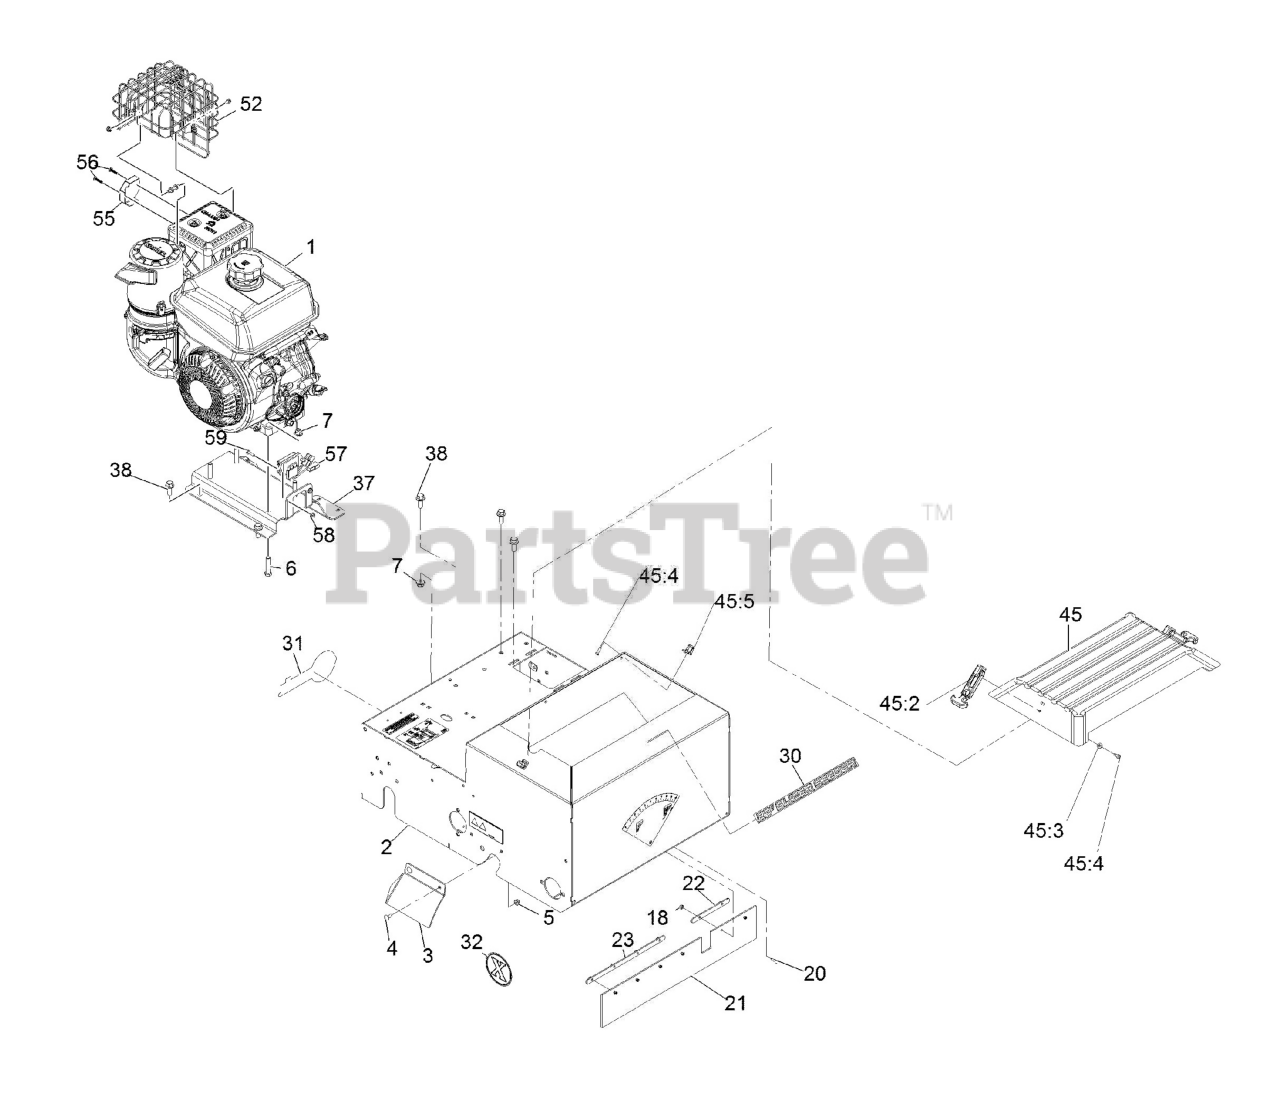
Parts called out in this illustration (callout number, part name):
2	FRAME ASM
4	SCREW-CARR
6	SCREW-HH
7	NUT-HF, NI
18	NUT-LOCK
20	SCREW-SHH
21	GUARD-DUST
22	PLATE-RETAINER
23	PLATE-RETAINER
30	Decal-Slicer Seeder Logo
31	DECAL, EXMARK LOGO
32	Decal-X-Logo
37	PLATE-ENGINE
38	SCREW-HHF 3/8-16 X 1
45	SEEDER COVER KIT
45:2	LATCH-RUBBER
45:3	WASHER-FLAT
45:4	SCREW-PPH
45:5	LATCH-KEEPER
52	GUARD-MUFFLER
55	DEFLECTOR-EXHAUST
56	Screw-PPH
57	Regulator
58	NUT-LOCK, FLANGE
59	SCREW-HWH
